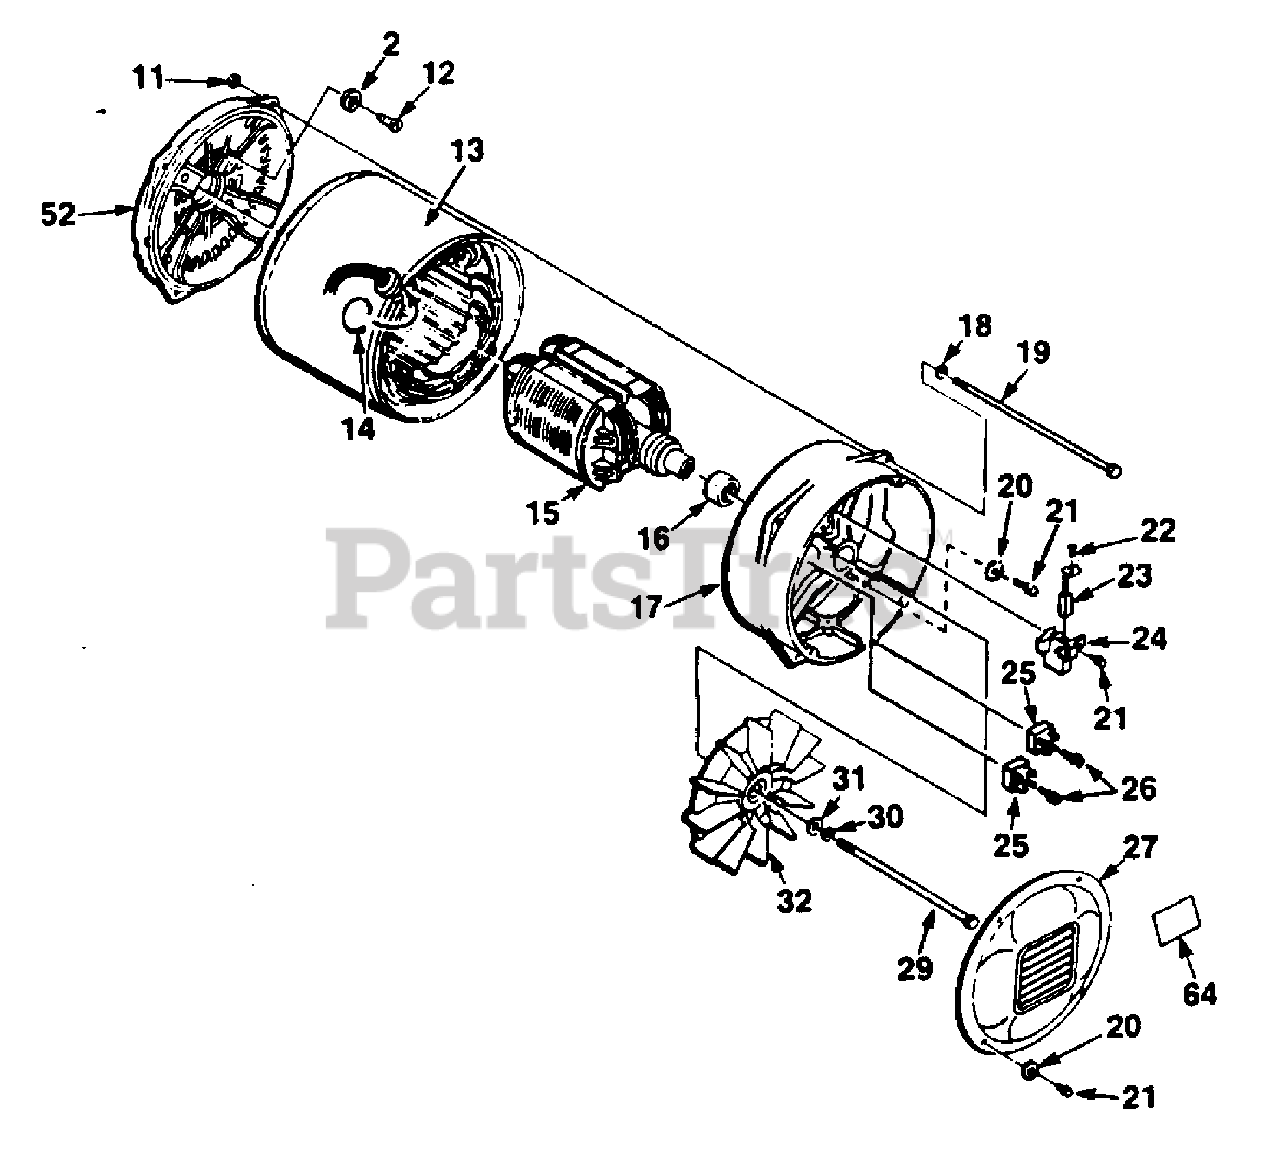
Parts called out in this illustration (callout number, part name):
2	WASHER- Lock Int. 5/16
11	NUT-Hex 1/4-20
12	SCREW-Hex hd., 5/16-24
13	STATOR & SHELL
14	TIE-Cable
16	BEARING
17	BRUSH HEAD
18	WASHER-Lock
19	BOLT-Stator
20	WASHER-Lock Int. #8
21	SCREW- Thread forming
22	SCREW- Mach round hd.
24	BRUSH HOLDER
25	RECTIFIER
26	SCREW-Hex taptite, 8-32 x 3/4"
27	COVER-Brush head
29	BOLT- Rotor .312-24 x 6 1/2"
30	WASHER- Lock 5/16"
31	WASHER-Flat 5/16"
52	GROMMET- Isolator
64	DECAL- Warning
